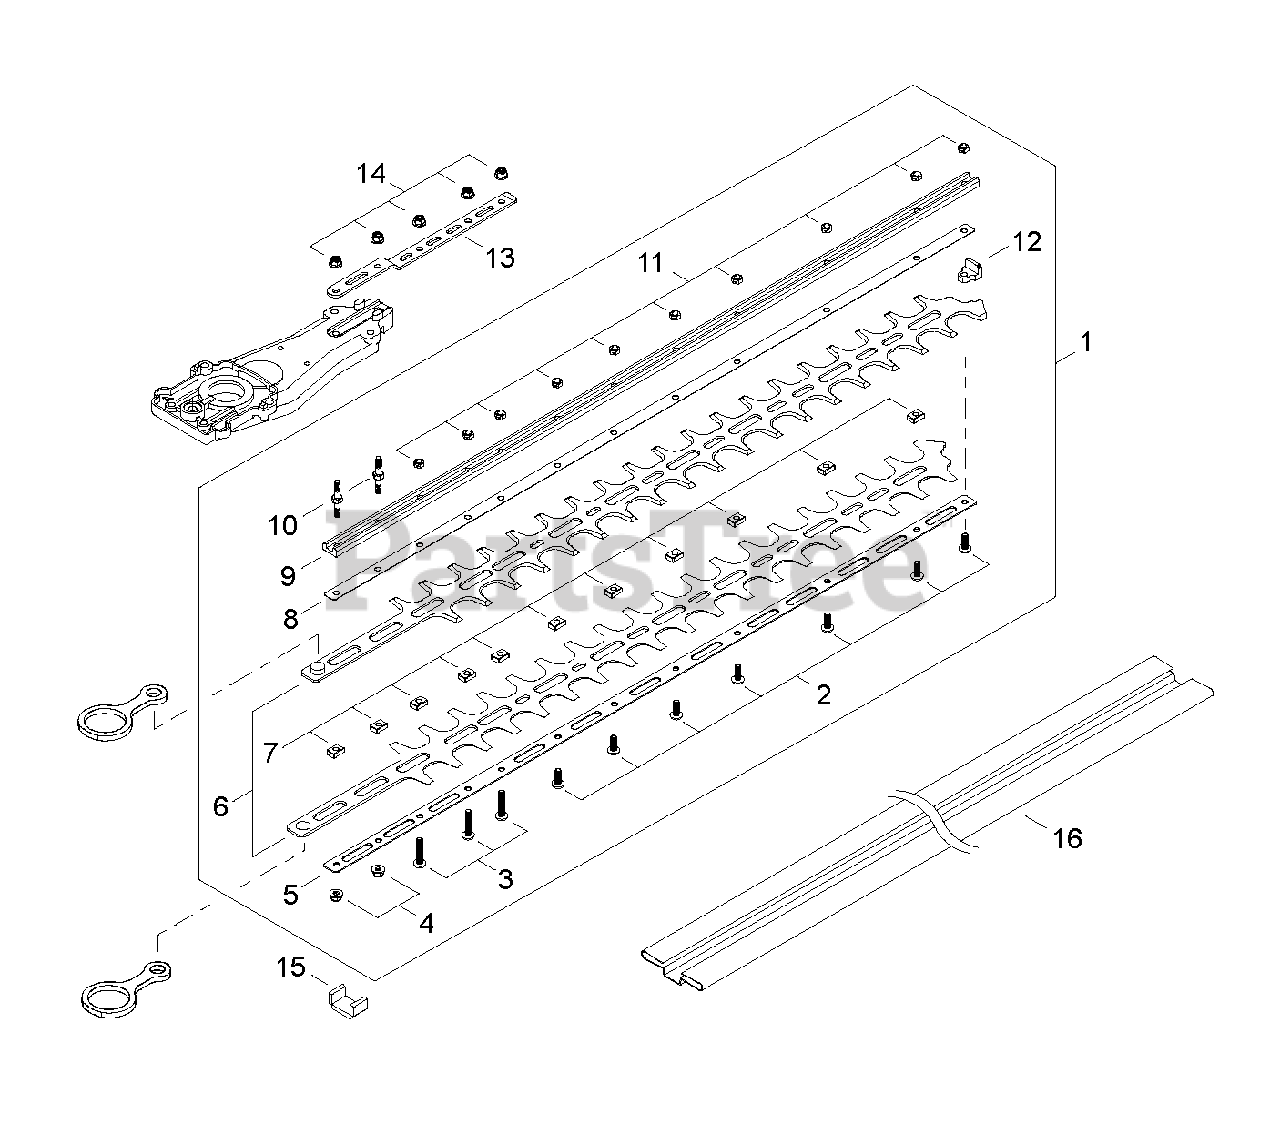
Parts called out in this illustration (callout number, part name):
1	CUTTER ASSY, 30"
2	BOLT M5×14
3	BOLT M5×25
4	NUT M5
5	PLATE, LOWER
6	BLADE, 30"
7	SPACER
8	PLATE, UPPER
9	GUIDE BAR, 30"
10	STUD, MOUNTING M5
11	NUT, LOCK M5
12	BLOCK
13	BRACKET, CUTTER
14	NUT M5
15	PACKING, FELT
16	SCABBARD 30"
